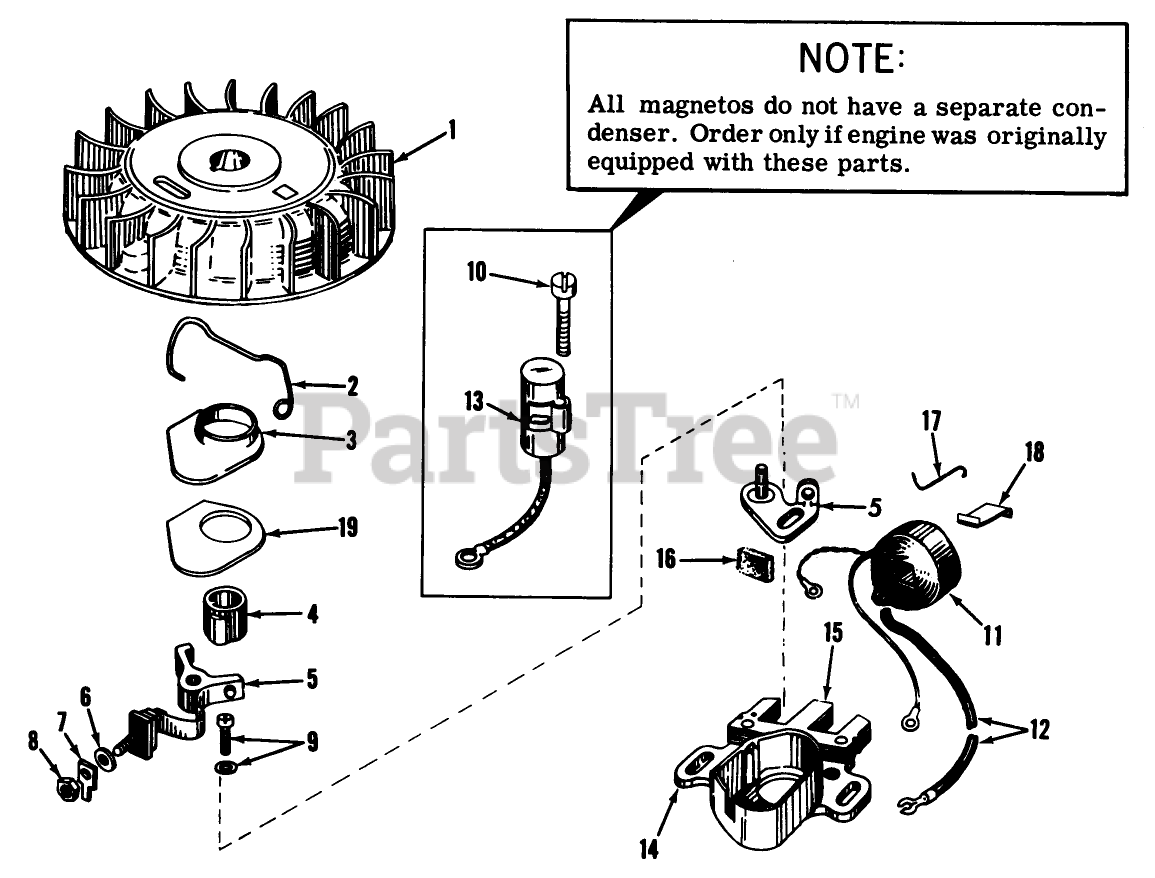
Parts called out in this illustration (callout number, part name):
1	Flywheel
2	Spring Breaker Box
3	Cover, Dust
4	Cam-Breaker
5	Breaker Assv.
6	Washer
7	Terminal
8	DECAL
9	Breaker Screw
10	Condenser Screw
11	Coil Assy., (Inc. Ref. Nos. 12, 13 18)
12	Wire, Lead
13	Condenser
14	Core Plate
15	A Stator Assy. (Incl. Nos. 5 thru 14, 16, 17 18)
16	Felt,Cam Wiper
17	Clip, Coil
18	Spring Coil Wedge
19	Gasket Dust
